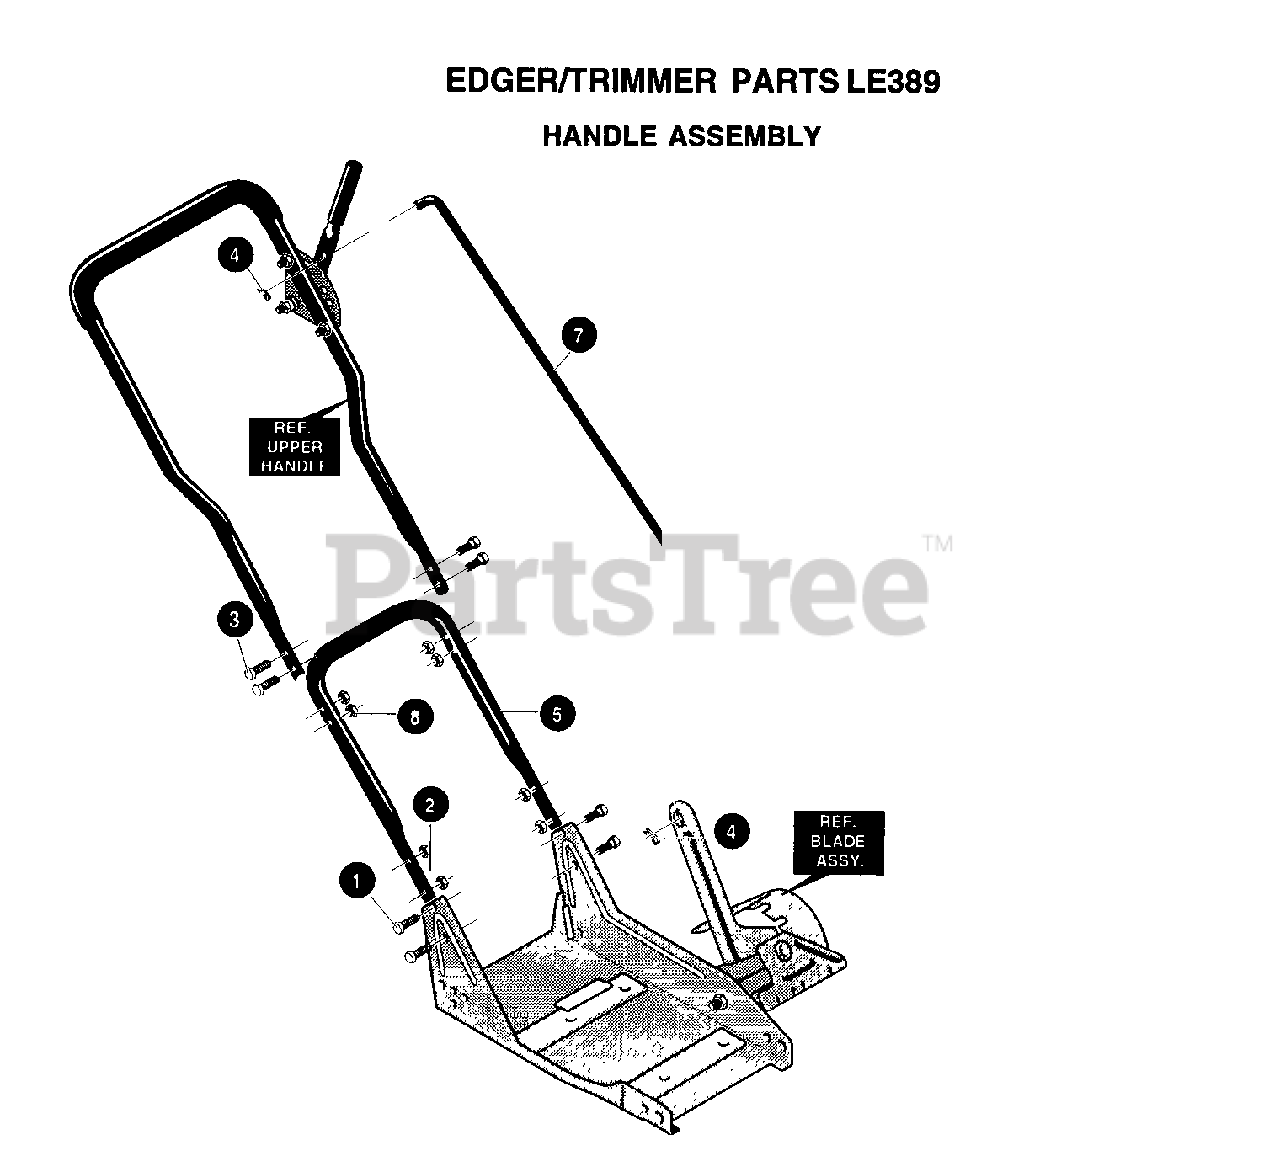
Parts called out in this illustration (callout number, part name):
1	Screw, 5/16-18 x .63
2	Nut, 5/16-18 Reghexctrlk
3	Carr. Bolt, 5/16-18 x 1.63
4	Hair Pin .072 Dia x 1.13Lg
5	Lower Handle
7	Control Rod
8	Nut, 5/16-18 Reghexctrlk
